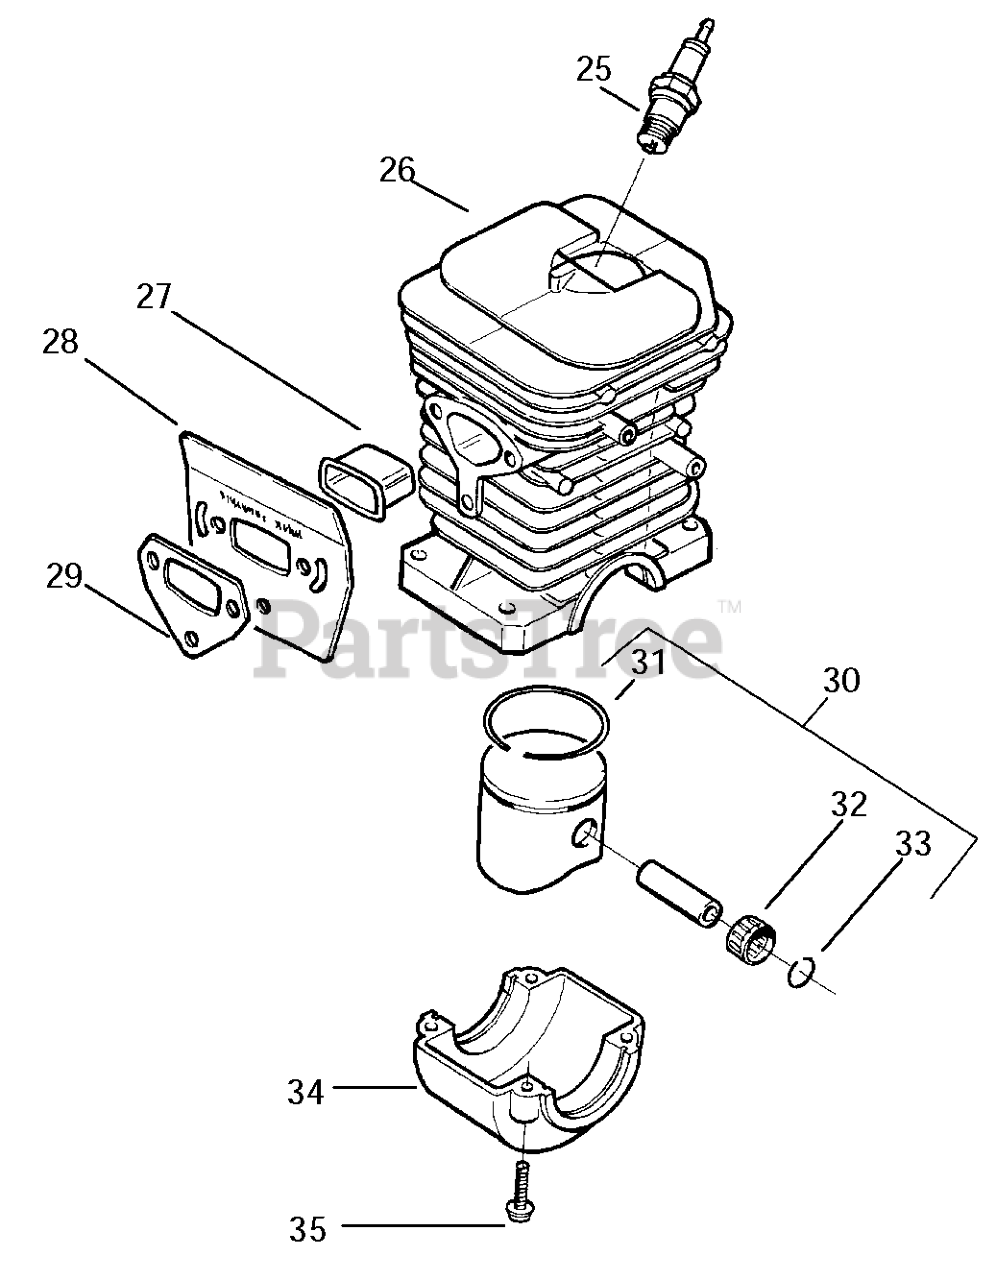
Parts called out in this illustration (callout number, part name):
25	Spark Plug (RCJ--7Y)
26	CYLINDER ASSY/136
27	HEAT INSULATOR
28	MUFFLER PLATE
30	PISTON KIT/136
31	PISTON RING 36
32	Piston Pin Bearing
33	C-CLIP,PSTN PIN 36/41
34	CAP-CRANKSHAFT
35	SCREW-M5-0.8 X 25MM(TAP)
